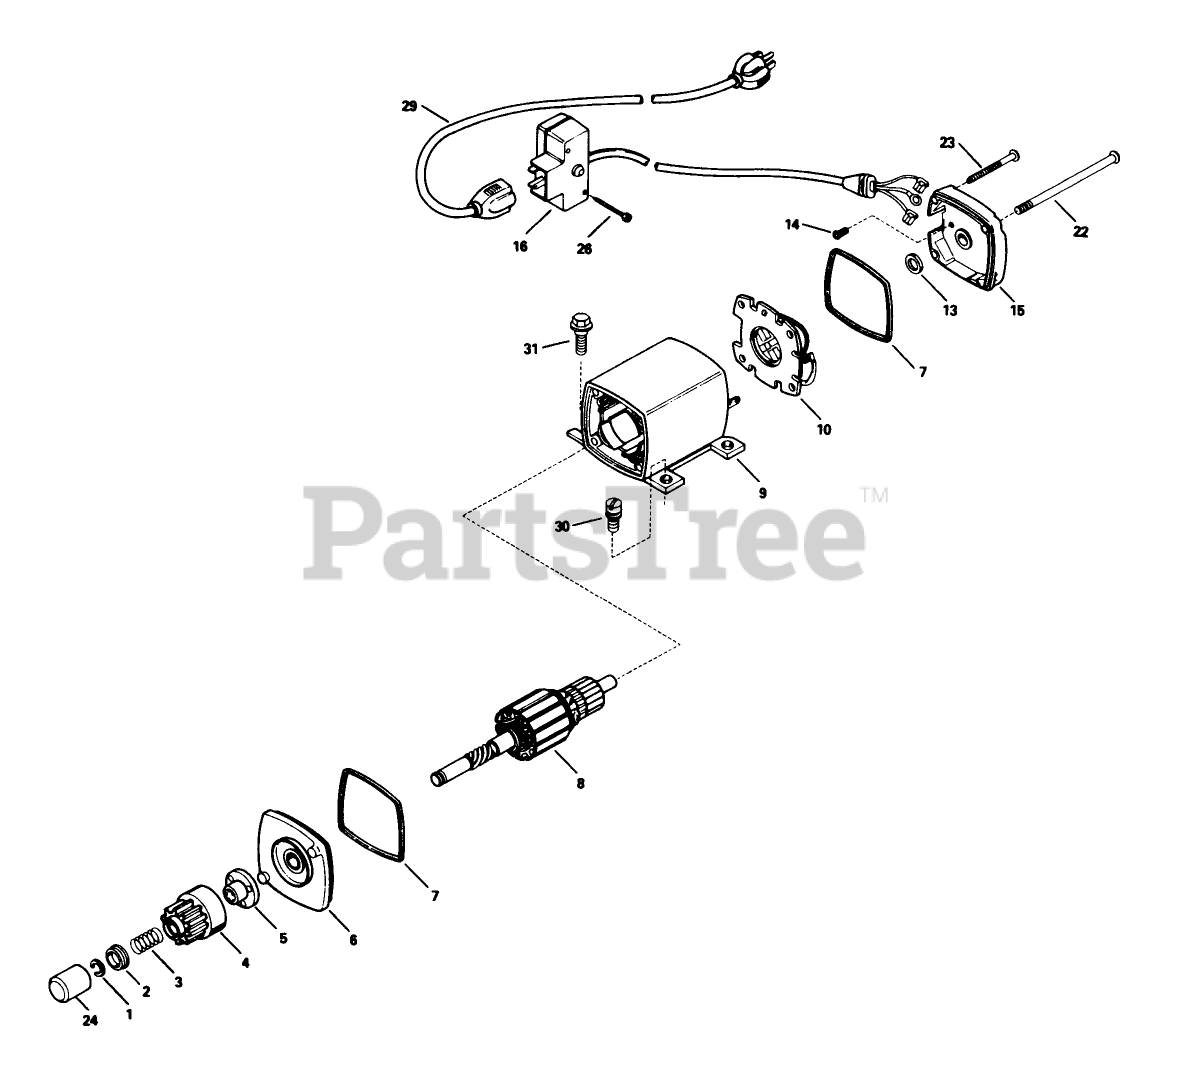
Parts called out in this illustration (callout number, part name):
1	Ring-Retainer
2	Retainer-Spring
3	Spring-Anti Drift
4	Gear
5	Nut-Engaging
6	Cap Assembly-Cap End (Incl. Ref. #7)
7	O-Ring
8	Armature
9	Housing Assy.
10	Card ASM
13	Washer-Thrust
14	Screw-Ground
15	Cap Assembly (Incl. Ref. #7)
16	Box Assembly-Switch (Incl. Ref. #26)
22	Bolt-Case
23	Screw-Ground
24	Cover-Dust
26	Screw
29	Cord-Extension
30	Screw
31	Screw (1/4-20x1/2)
